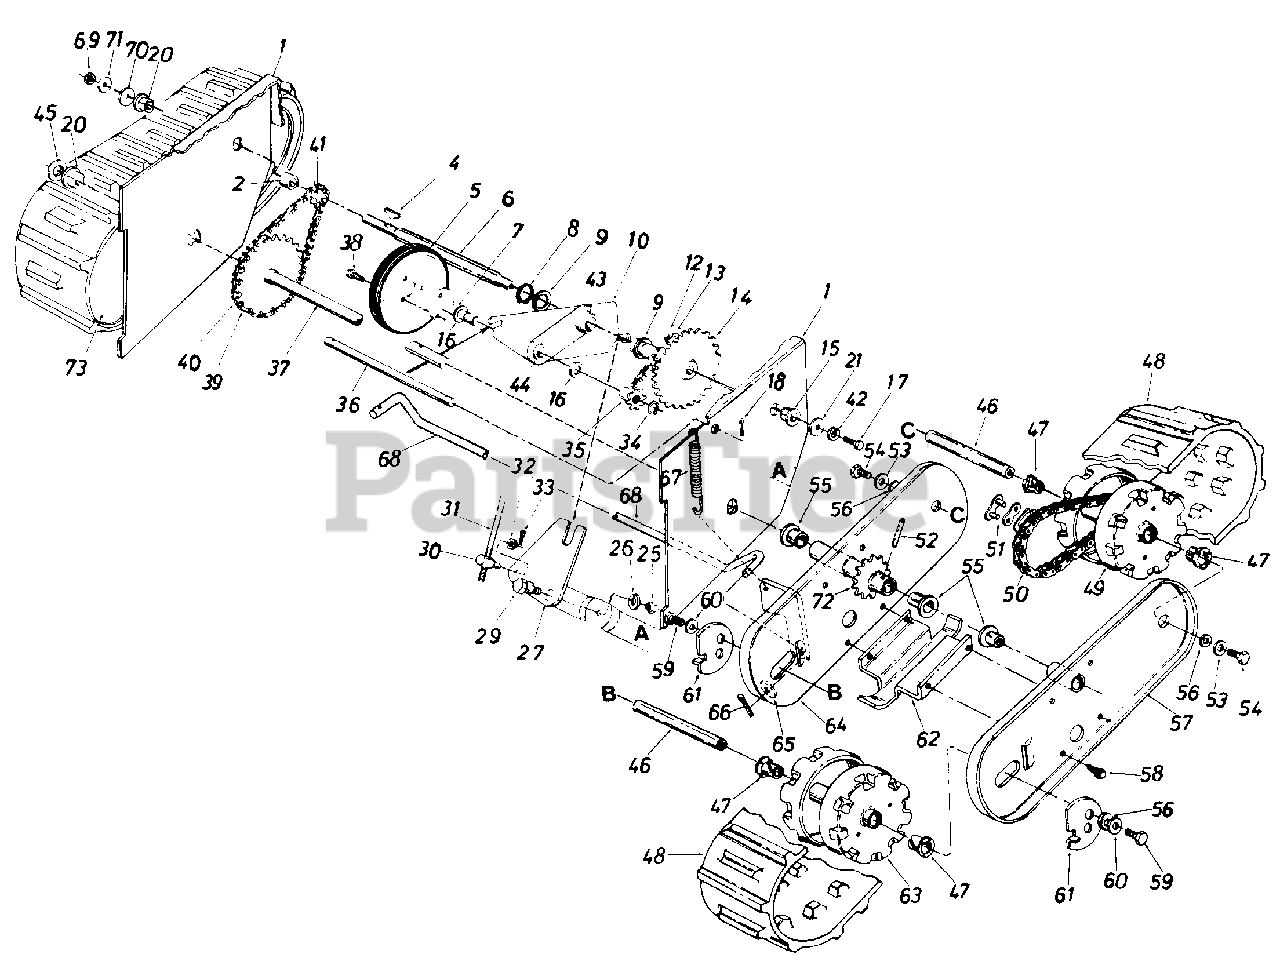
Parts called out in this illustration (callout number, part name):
1	Frame Ass'y.
2	Spacer .50" I.D. x .75" O.D. x.78" Lg.
4	#4 Hi-Pro Key 3/32 x 518" Dia.
5	Friction Wheel Ass'y.
6	Hex Shaft
7	Friction Wheel Mounting Plate Ass'y.
8	Snap Ring 1.00" Dia. Shaft
9	Fl-Wash. 1.00" x 1.63" O.D. x .03
10	Sliding Bracket Ass'y.
12	#41 Chain 1/2" Pitch x 35 Links
13	Master Link for #41 Chain
14	32 Teeth Sprocket Ass'y.
15	Hex Flange Brg. .630" I.D.
16	Fl-Wash. .62" I.D. x 1.00" O.D. x .06
17	Hex Lock Bolt 5/16-18 x .62" Lg.
18	Cotter Pin 3/32" Dia. x .75" Lg.*
20	Flange Brg. w/Flats .755" I.D.
21	Fl-Wash. .34" I.D. x 1.12" O.D. x .125
25	Hex Jam Nut 3/8-16 Thd.*
26	L-Wash. 3/8" I.D.*
27	Shifting Linkage Bracket
29	Shld. Bolt .625" Dia. x .170" Lg.
30	Adjustment Ferrule
31	Shifting Rod 5/16" Dia. x 32.50" Lg.
32	Fl-Wash. .34" I.D. x .64" O.D. x .06
33	Cotter Pin 3/32" Dia. x .75" Lg.*
34	Snap Ring .562" Dia. Shaft
35	Sprocket 7 Teeth x .50" Pitch
36	Shaft .50" Dia. x 9.50" Lg.
37	32 Teeth Wheel Shaft Ass'y.
38	Hex Wash. Hd. Self-Tap Scr. 5/16-24 x .50" Lg.
39	#420 Chain 1/2" Pitch x 39 Links
40	Master Link for #420 Chain
41	8 Teeth Center Sprocket
42	L-Wash. 5/16" I.D.
43	Plastic Bearing
44	Bronze Bearing
45	Fl-Wash. .76" I.D. x 1.49 O.D.
46	Wheel Shaft 5/8 x 4.25" Lg.
47	Flange Brg. .632" I.D.
48	Snow Track 5" x 48"
49	Drive Wheel Ass'y.
50	Chain #420 x 50 Pitch x 37 Links
51	Master Link #420
52	Spring Pin Spir. 1/4" Dia. x 1.50" Lg.
53	Bell-Wash. .345" I.D. x .88" O.D.
54	Hex Bolt 5/16-24 x .62" Lg.
55	Flange Brg. .757" I.D.
56	Fl-Wash. .510" I.D. x 1.0" O.D.
57	Outer Plate Ass'y.-L.H.
58	Hex Wash. S-Tap Scr. 1/4-20 x .50" Lg.
59	Hex Bolt 5/16-24 x .62" Lg.
60	Bell-Wash. .345" I.D. x .88" O.D.
61	Track Adjuster
62	Skid Shoe
65	Fl-Wash. .385" I.D. x .87" O.D.
66	Cotter Pin 1/8" x .75" Lg.
67	Extension Spring
68	Connecting Rod 3/8" Dia. x 12.12" Lg.
69	Hex Ins. L-Nut 1/2-20 Thd.
70	Fl-Wash. .53 I.D. x 1.25 O.D. x .10
71	Bell-Wash. .50 I.D. x 1.0 O.D. x .075
72	17T Sprocket Hub Ass'y.
73	Inner Plate Ass'y.-R.H.
